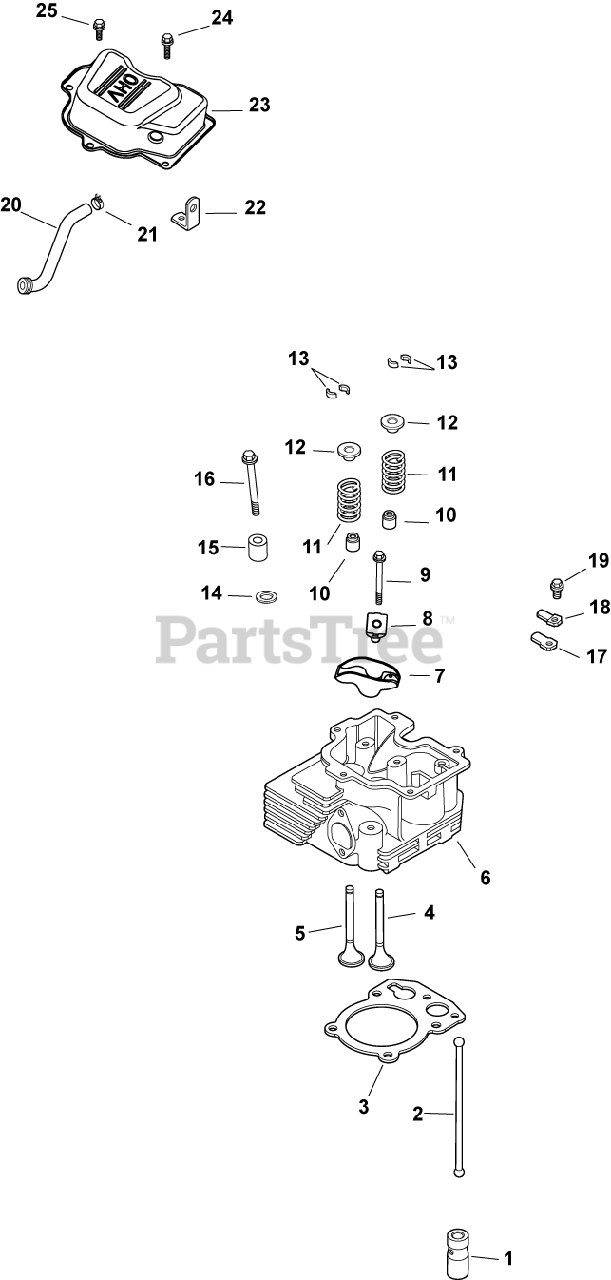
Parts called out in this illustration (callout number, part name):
1	LIFTER, HYDRAULIC VALVE-USE 25 351 10-S
2	ROD, PUSH
3	GASKET, CYLINDER HEAD
4	VALVE, EXHAUST
5	VALVE, INTAKE
6	KIT, HEAD, CYLINDER
7	ARM, ROCKER
8	PIVOT, ROCKER ARM
9	SCREW, FLG M6X1.0X34
10	SEAL, VALVE STEM - (#2503214S)
11	SPRING, VALVE
12	RETAINER, VALVE SPRING - USE 25 173 28-S
13	KIT, RETAINER
14	WASHER, FLAT 13/32"
15	SPACER, HEAD BOLT EXHAUST PORT
16	SCREW, CYLINDER HEAD (M10 X 80)
17	REED, BREATHER
18	RETAINER, REED
19	SCREW, FLG THD FRM M5X.8X10
20	HOSE, BREATHER
21	CLAMP, HOSE (KM)-USE 25 237 31-S
23	COVER, ROCKER
24	SCREW,FLG THD FRM M6X1.0X20-(#25086396S)
25	SCREW,FLG THD FRM M6X1.0X16-(#25086397S)
1201602-S	VALVE, EXHAUST (.25 MM)
1201702-S	VALVE, INTAKE (.25 MM)
4746807-S	WASHER, FLAT 13/32" - DISCONTINUED
